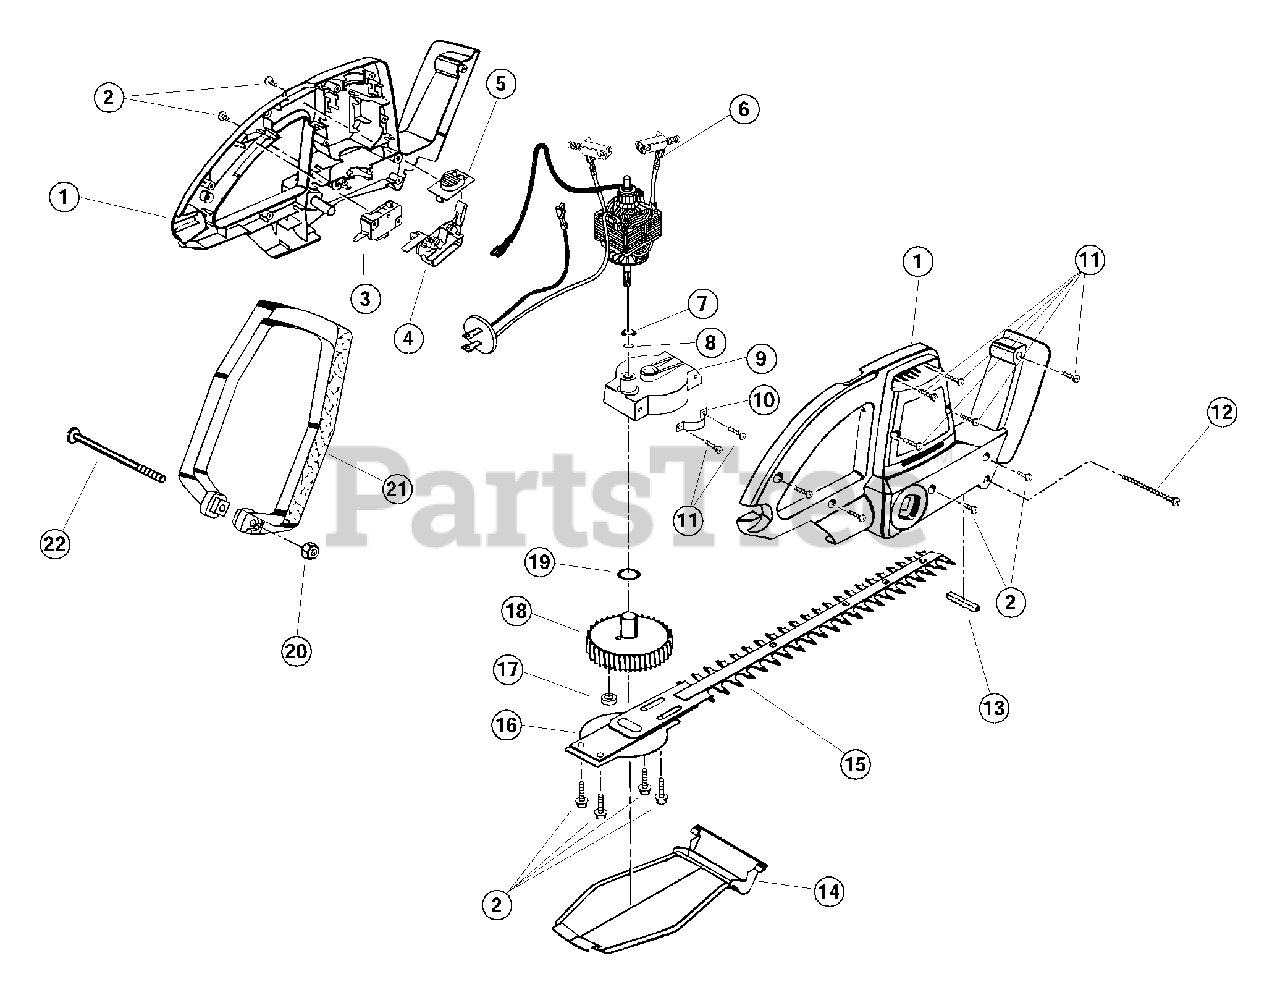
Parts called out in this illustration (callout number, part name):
1	Housing Assembly
4	Switch Trigger Assembly
5	Lock-On Button
6	Motor Assembly
7	Spring Washer
9	Gear Housing w/Bearings
10	Bearing Strap
13	Blade Seal
14	Blade Cover
15	Blade Assembly
16	Grease Cover
17	Drive Washer
18	Gear Assembly (HT816r)
20	Lock Nut
21	Front Handle
